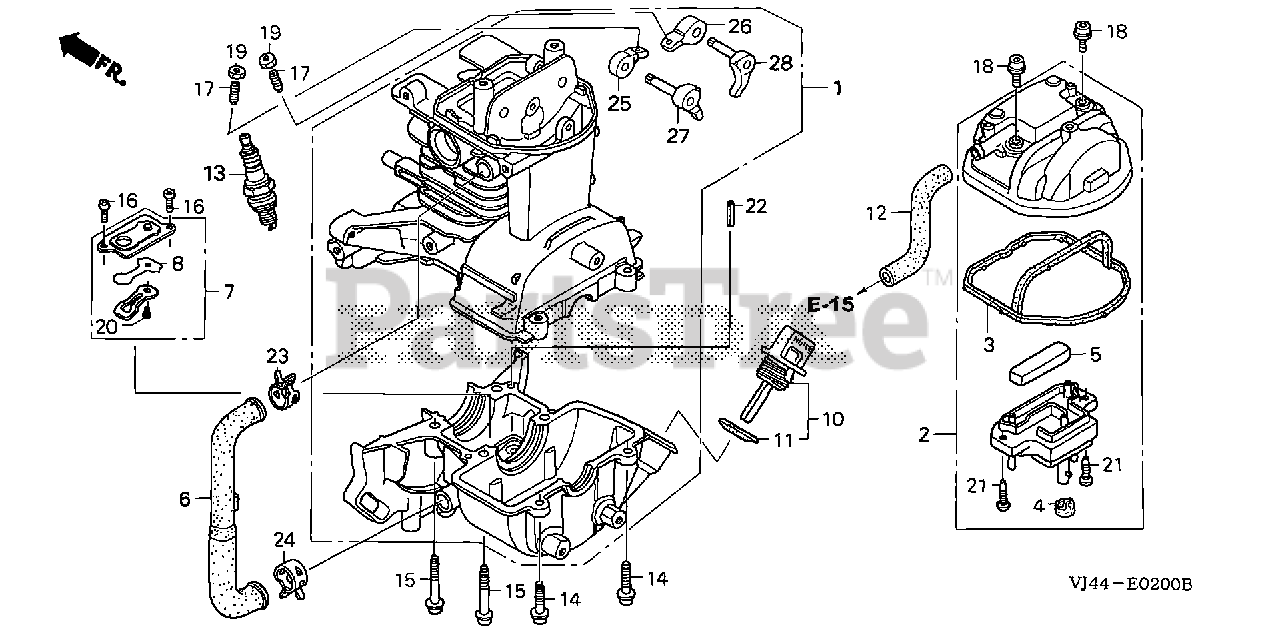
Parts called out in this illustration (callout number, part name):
1	CRANKCASE SET
2	COVER, CYLINDER HEAD
3	SEAL, HEAD COVER
4	GROMMET, HEAD COVER
5	FILTER, BREATHER
7	PLATE ASSY., OIL OUTLET VALVE
8	VALVE, OIL OUTLET
10	CAP ASSY., OIL FILLER
11	GASKET, OIL FILLER CAP
12	TUBE, BREATHER
13	SPARK PLUG (CMR4H) (NGK)
13	SPARK PLUG (CMR5H) (NGK)
13	SPARK PLUG (CMR6H) (NGK)
14	BOLT, SOCKET (5X20)
15	BOLT, SOCKET (5X30)
16	SCREW, PAN (4X8)
17	SCREW, TAPPET ADJUSTING
18	BOLT, SOCKET (5X12)
19	NUT, TAPPET ADJUSTING
20	SCREW, PAN (3X5)
21	SCREW, TAPPING (4X12)
22	PIN, SPRING (4X10)
23	CLAMP, TUBE (D12)
24	CLAMP, TUBE (D13)
25	ARM, IN. VALVE ROCKER
26	ARM, EX. VALVE ROCKER
27	LIFTER, IN. VALVE
28	LIFTER, EX. VALVE
